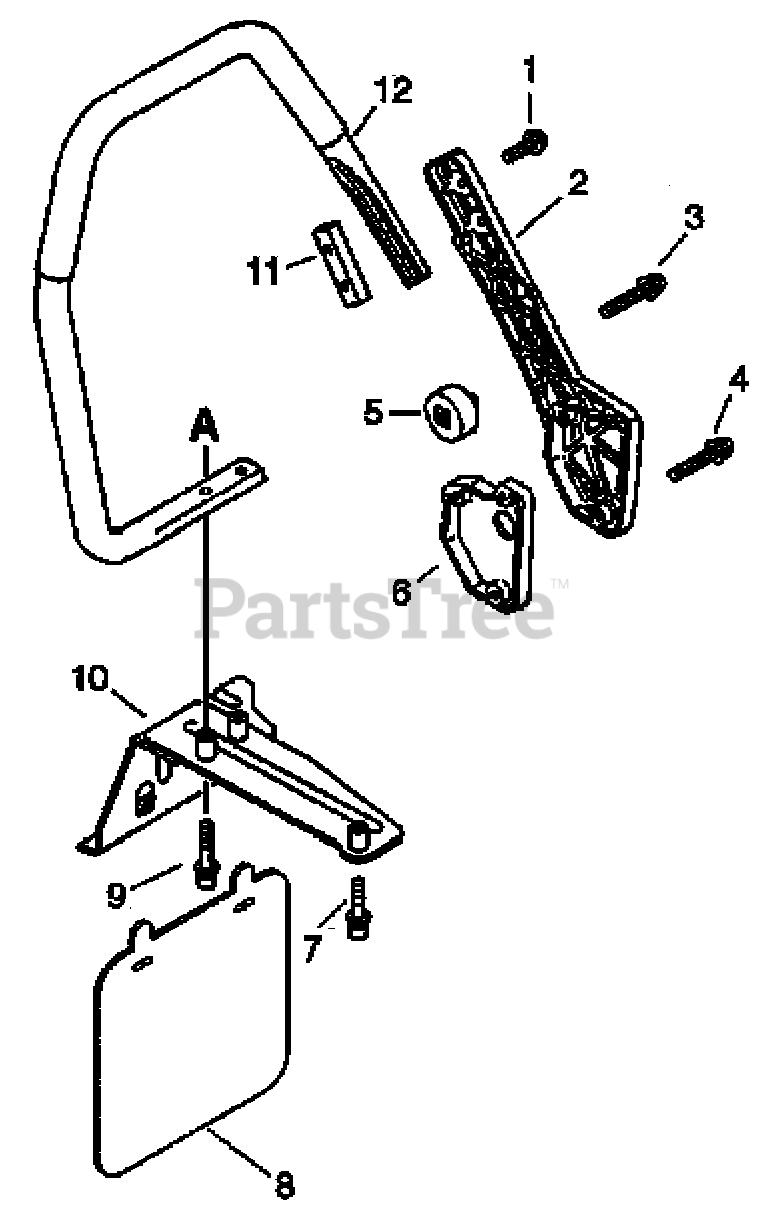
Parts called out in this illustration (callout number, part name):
1	SCREW - 5X20
2	BRACKET, HANDLE
3	SCREW - 5X30
4	SCREW - 5X35
5	ADAPTER, CUSHION L-L
7	SCREW - 5X30
9	SCREW - 5X35
10	BRACKET, HANDLE
12	HANDLE - FRONT
